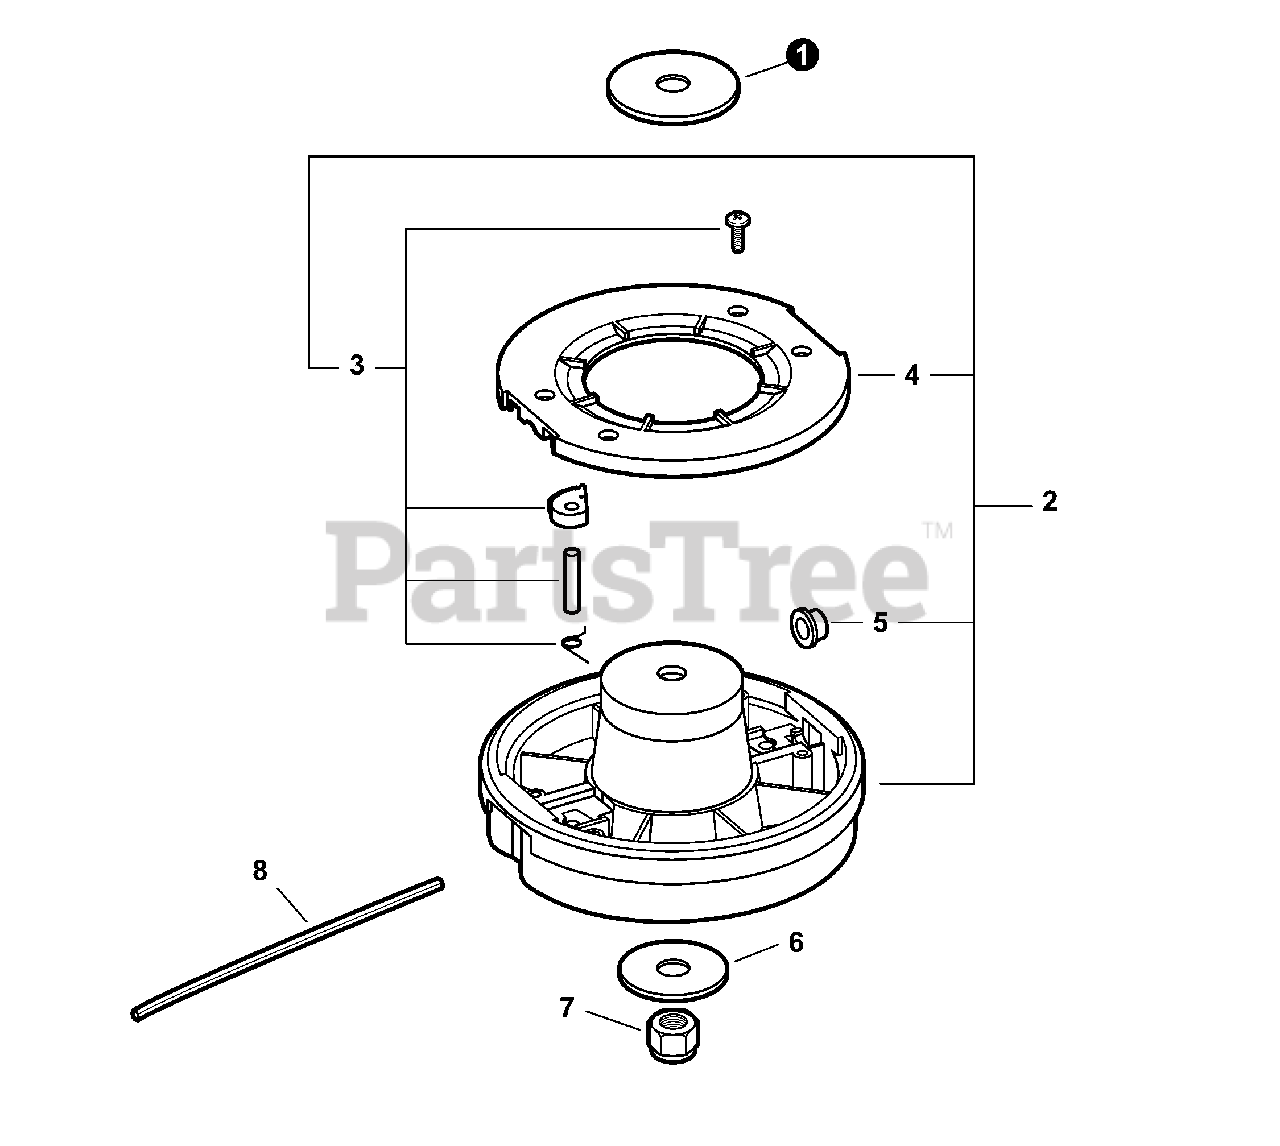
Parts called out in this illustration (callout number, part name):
2	TRIMMER HEAD, RAPID LOADER
3	PAWL KIT
4	COVER, TOP
6	WASHER 10
7	NUT, LOCK
8	LINE, TRIMMER - 0.080 DIA.
